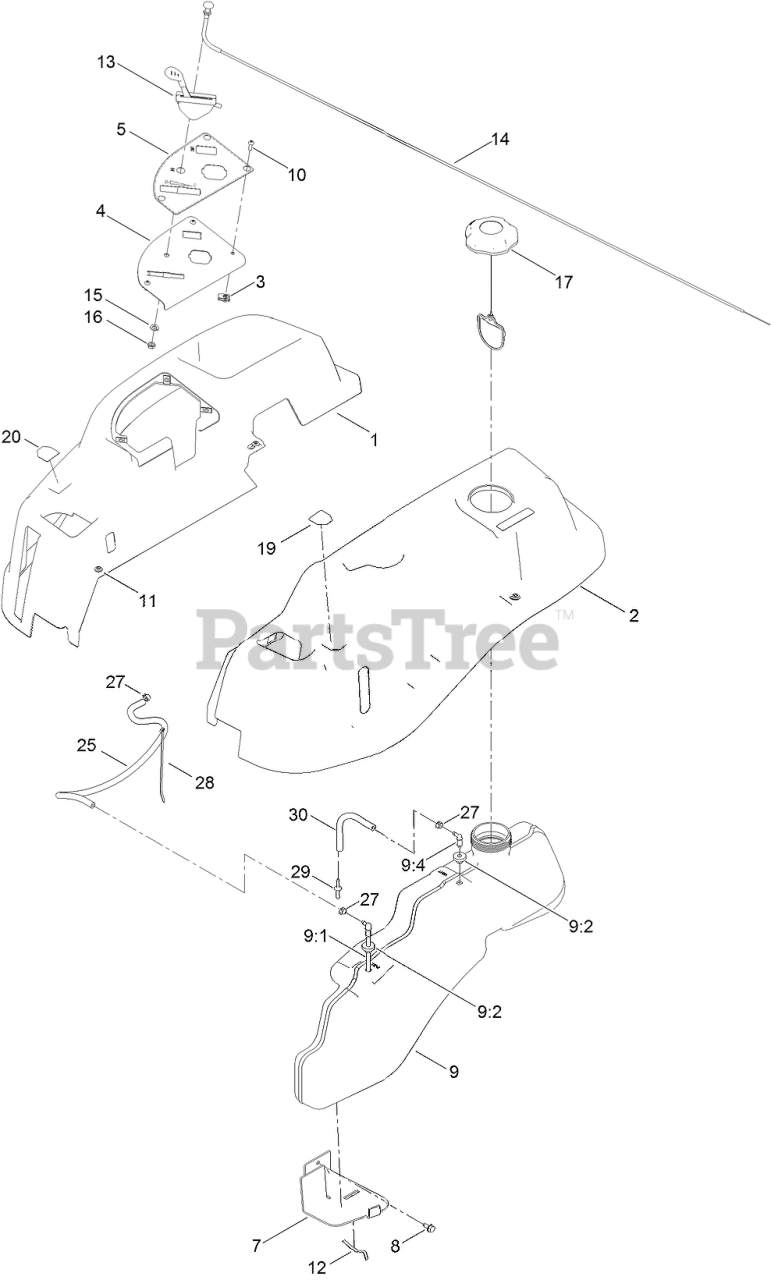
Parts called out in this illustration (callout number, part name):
1	POD-RH
2	POD-LH
4	PLATE-CONTROL
5	DECAL-PANEL, CONTROL
7	SUPPORT-TANK, FRONT
8	SCREW-HWHTF
9	FUEL TANK ASM
9:1	CONNECTOR-ELBOW, 90 DEG
9:2	BUSHING
9:4	FITTING-PLASTIC
10	SCREW-PRH
11	SCREW-SHOULDER
12	SPRING
13	CABLE-THROTTLE
14	CABLE-CHOKE
15	WASHER-LOCK
16	NUT-HJ
17	CAP-FUEL, RATCHETING
19	DECAL-LEVER, CONTROL (LH)
20	DECAL-LEVER, CONTROL (RH)
25	HOSE-FUEL
27	CLAMP-HOSE
28	TIE-CABLE
29	ADAPTOR-ORIFICE
30	HOSE-FUEL
